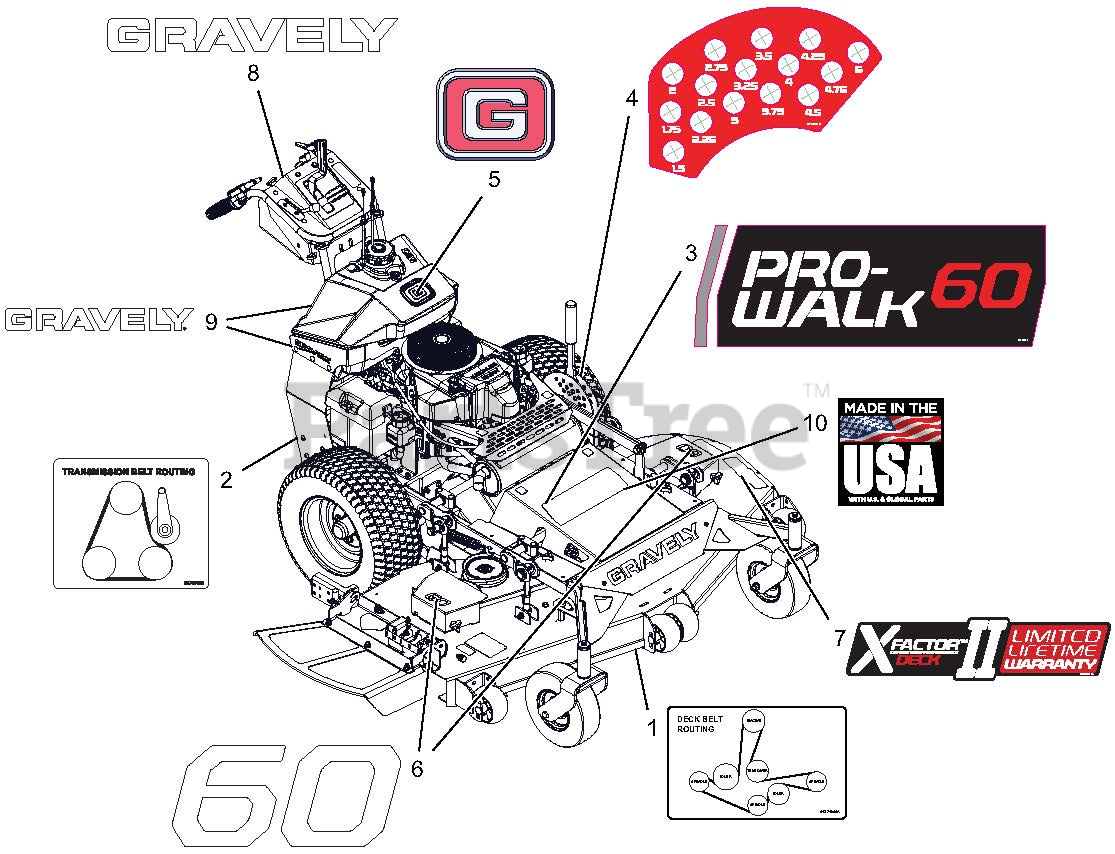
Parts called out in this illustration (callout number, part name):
1	DECAL, BELT ROUTING
2	DECAL, HYDRO BELT 36 PROSTANCE
3	DECAL, PRO WALK 60"
4	DECAL, HOC
5	DECAL, GRAVELY BRAND
6	DECAL, 60"
7	DECAL, X-FACTOR DECK
8	DECAL, 9.5" GRAVELY LOGO
9	DECAL, 6.5" GRAVELY LOGO
10	DECAL, MADE IN USA
